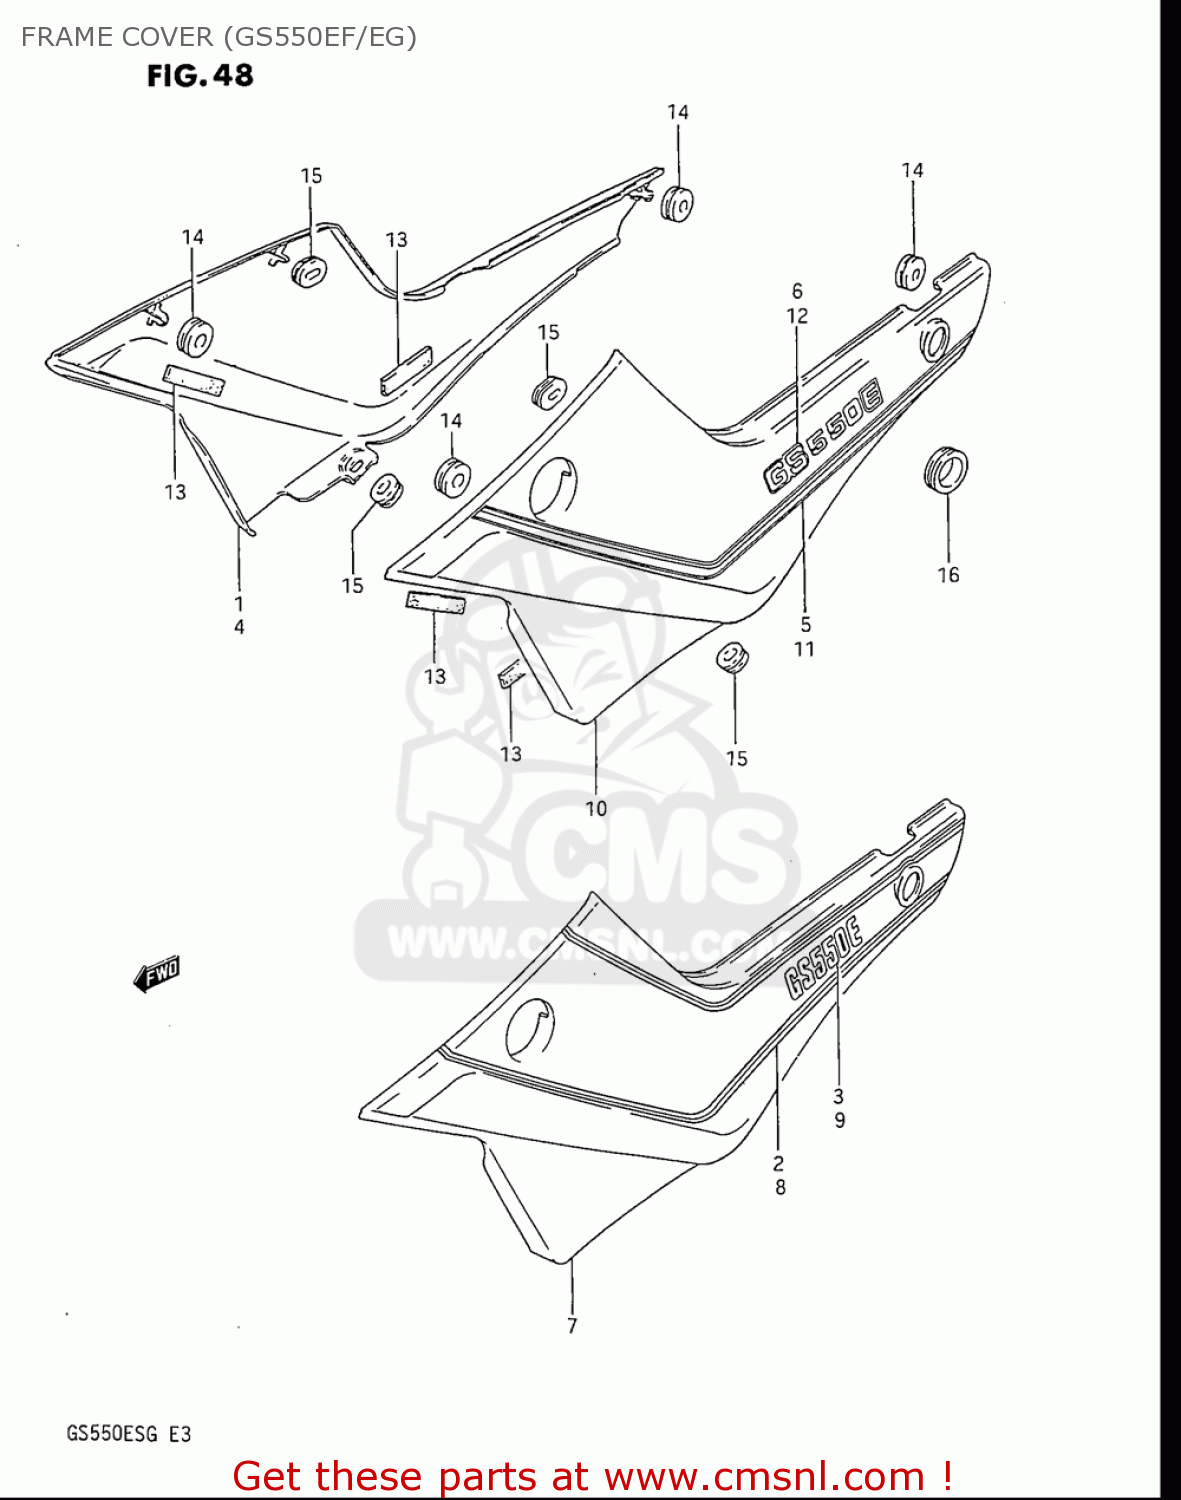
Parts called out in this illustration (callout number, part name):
1	COVER,FRAME,R
2	TAPE SET,FRAME COVER,RIGHT
7	COVER,FRAME,L
13	RUBBER,FRAME COVER
14	CUSHION
15	CUSHION
16	GROMMET,SEAT LOCK HOLE
